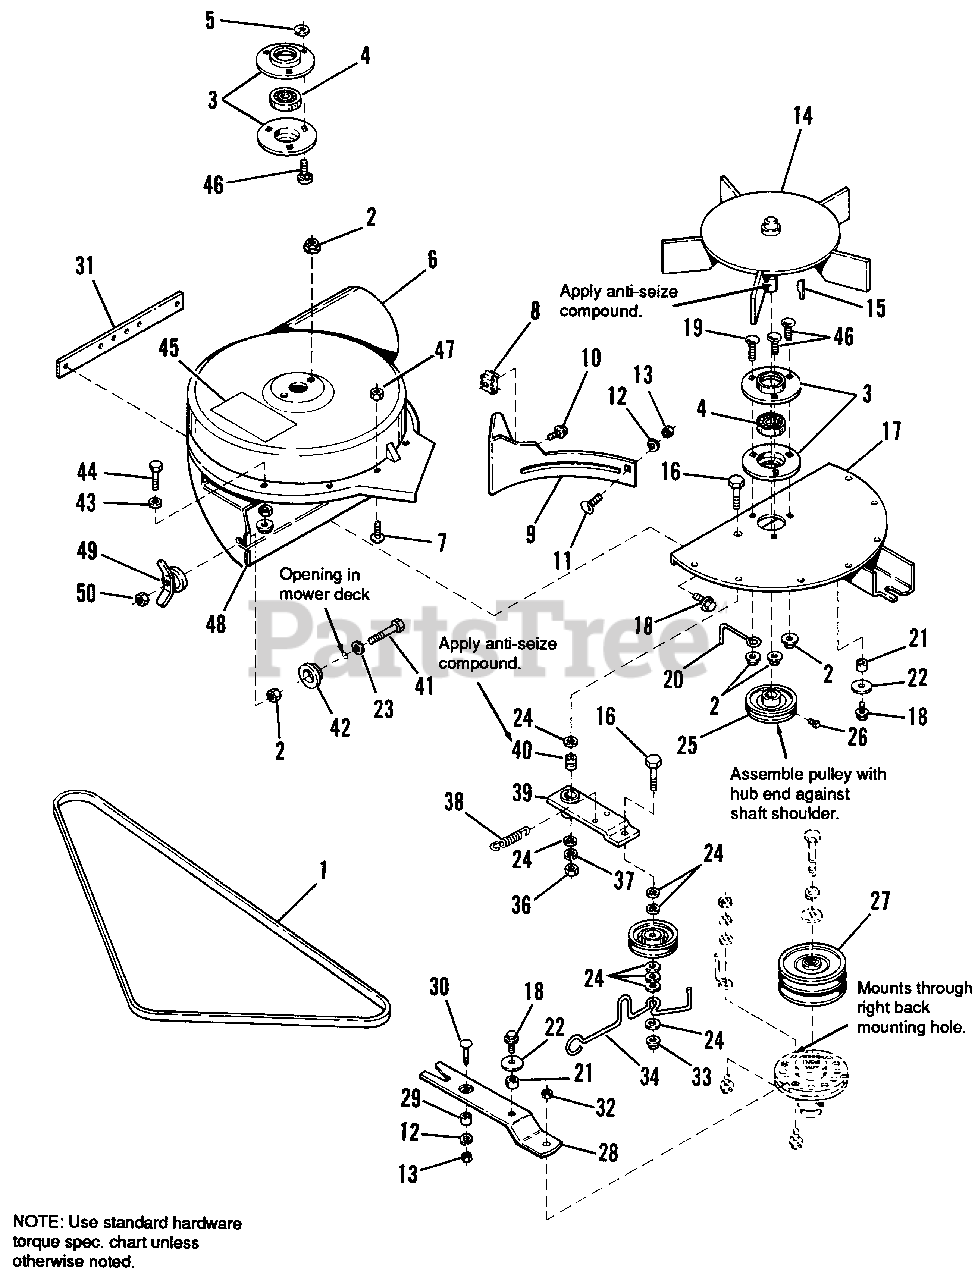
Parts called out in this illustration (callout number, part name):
1	BELT
2	NUT, Flange Lock, 5/16-18
3	BEARING, Retainer
5	PUSHNUT, 5/16
6	HOUSING ASSY., (Incl. Ref. No. 45)
7	CAPSCREW, Hex, 1/4-20 x 5/8
8	NUT, Retainer, 14-20
10	SCREW, Whizlock, 1/4-20 x 1/2
11	CARRIAGE BOLT, 1/4-20 x 5/8
12	LOCKWASHER, 1/4
13	NUT, Hex, Full, 1/4-20
15	KEY, Woodruff
16	CAPSCREW, 3/8-16 x 1-3/4
17	PLATE ASSY.
18	SCREW, Taptite, 1/4-20 x 5/8
19	CARRIAGE BOLT, 5/16-18 x 7/8
22	WASHER, Special
23	WASHER, Flat, 5/16
24	WASHER, Flat, 3/8
25	PULLEY, Driven
26	SETSCREW, 5/16-18 x 1/2
27	PULLEY ASSY.
30	CARRIAGE BOLT, 1/4-20 x 1-1/4
31	STRIP, Reinforcement
32	NUT, Hex, Jam Lock, 5/16-18
33	NUT, Hex, Flange Lock, 3/8
34	LEVER, Belt, Retainer
36	NUT, Hex, Full, 3/8-16
37	LOCKWASHER, 3/8
38	SPRING, Tension
39	IDLER ARM ASSY.
40	SPACER
41	CAPSCREW, Hex, 5/16-18 x 2-1/2
43	WASHER, Plain, 1/4
44	CAPSCREW, Hex, 1/4-20 x 1
45	DECAL, Danger
46	CARRIAGE BOLT, 5/16-18 x 3/4
47	LOCKNUT, Hex, Whiz, Flange, 1/4-20
48	NUT, Hex, Flange Lock, 1/4-20
49	WINGNUT ASSY.
50	NUT, Hex, Full, Lock, 5/16-18
